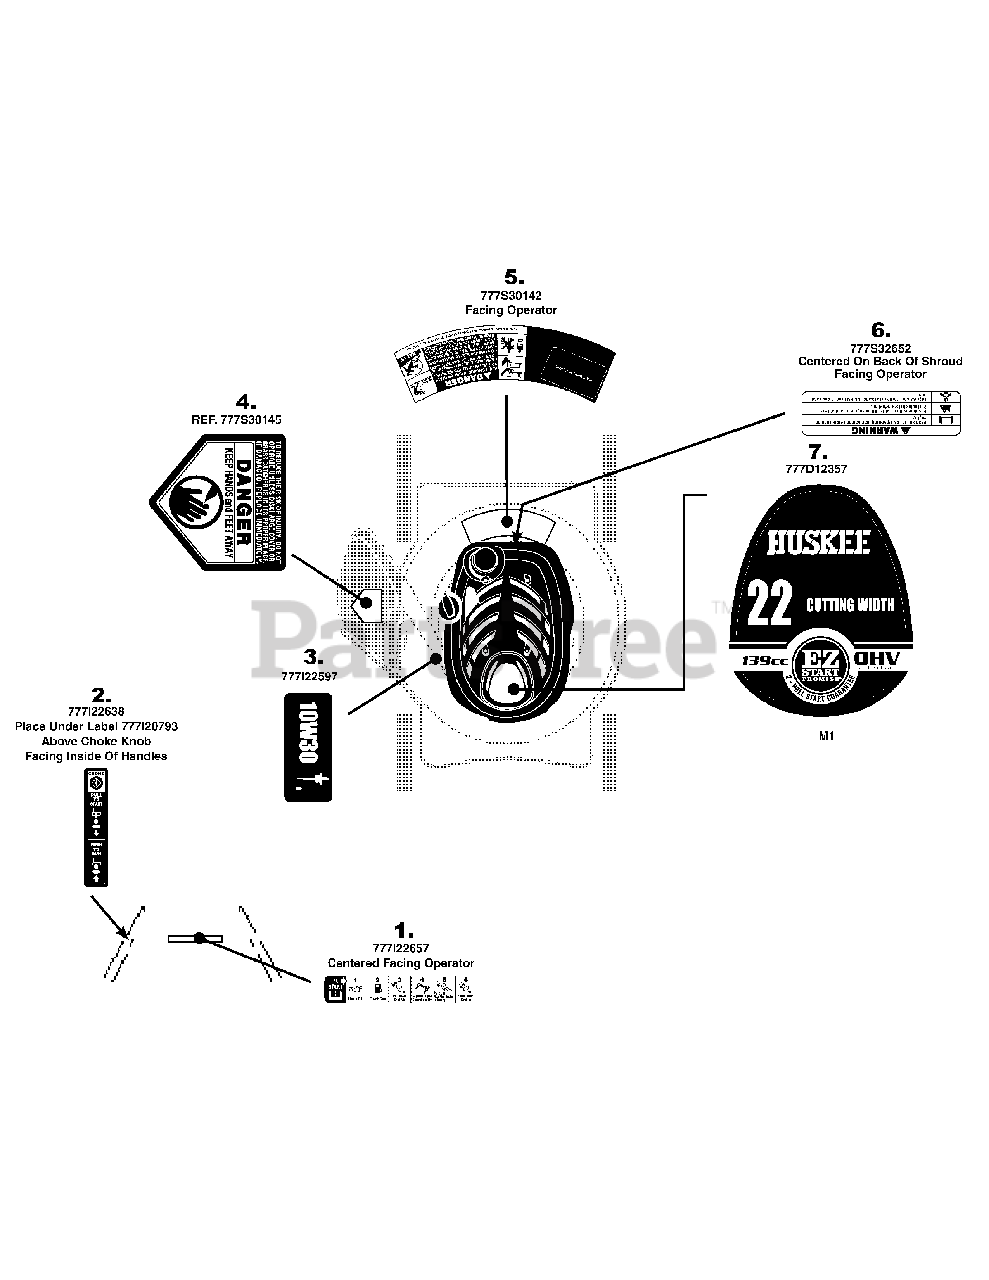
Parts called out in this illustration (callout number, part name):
1	LABEL-MOWER HANDLE
2	LABEL-MOWER HANDLE:CHOKE START/RUN
3	LABEL:MOWER SHROUD
4	LABEL
5	LABEL-DANGER CURVE
6	LABEL:MOWER:ENGINE SHROUD
7	LABEL-MOWER SHROUD HUSKEE 22"
